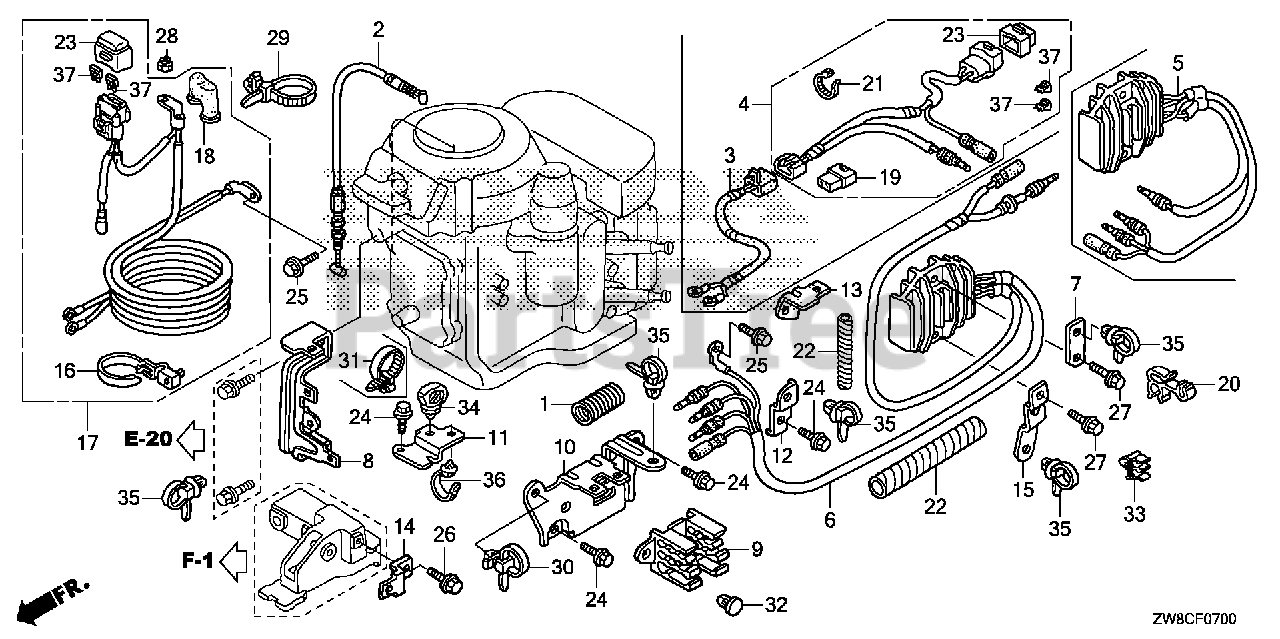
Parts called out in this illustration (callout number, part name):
2	CABLE, NEUTRAL STARTING
3	WIRE ASSY., BATTERY CHARGE
4	RECEPTACLE ASSY., CHARGE
5	RECTIFIER ASSY., REGULATOR
7	BRACKET, CLIP F
8	BRACKET, CONNECTOR (A)
9	BRACKET, CONNECTOR (B)
10	BRACKET, CONNECTOR (C)
11	BRACKET, STARTER CABLE
12	BRACKET, CLIP B
13	BRACKET, FUSE CASE
14	BRACKET, CONNECTOR (D)
15	BRACKET, E-CLIP
19	CONNECTOR, DUMMY
20	CLAMP, DISTRIBUTOR WIRE
21	TIE, CABLE (NATURAL 2.4X92) Use up to Frame SN 1300359.
22	TUBE, SPIRAL A
23	COVER ASSY., FUSE (20A)
24	BOLT, FLANGE (6X14) (CT200)
26	BOLT, FLANGE (6X12) Use from Frame SN 1005249.
27	BOLT, FLANGE (6X26) (CT200)
30	STRAP, CABLE (118MM) *NH1L* (Honda Code 1170653). (BLACK)
32	CLIP, ANCHOR
33	CLIP, FUEL TUBE
34	CLIP, HARNESS
35	CLIP, HARNESS BAND (151.5MM) (NATURAL)
37	FUSE, BLADE (20A)
